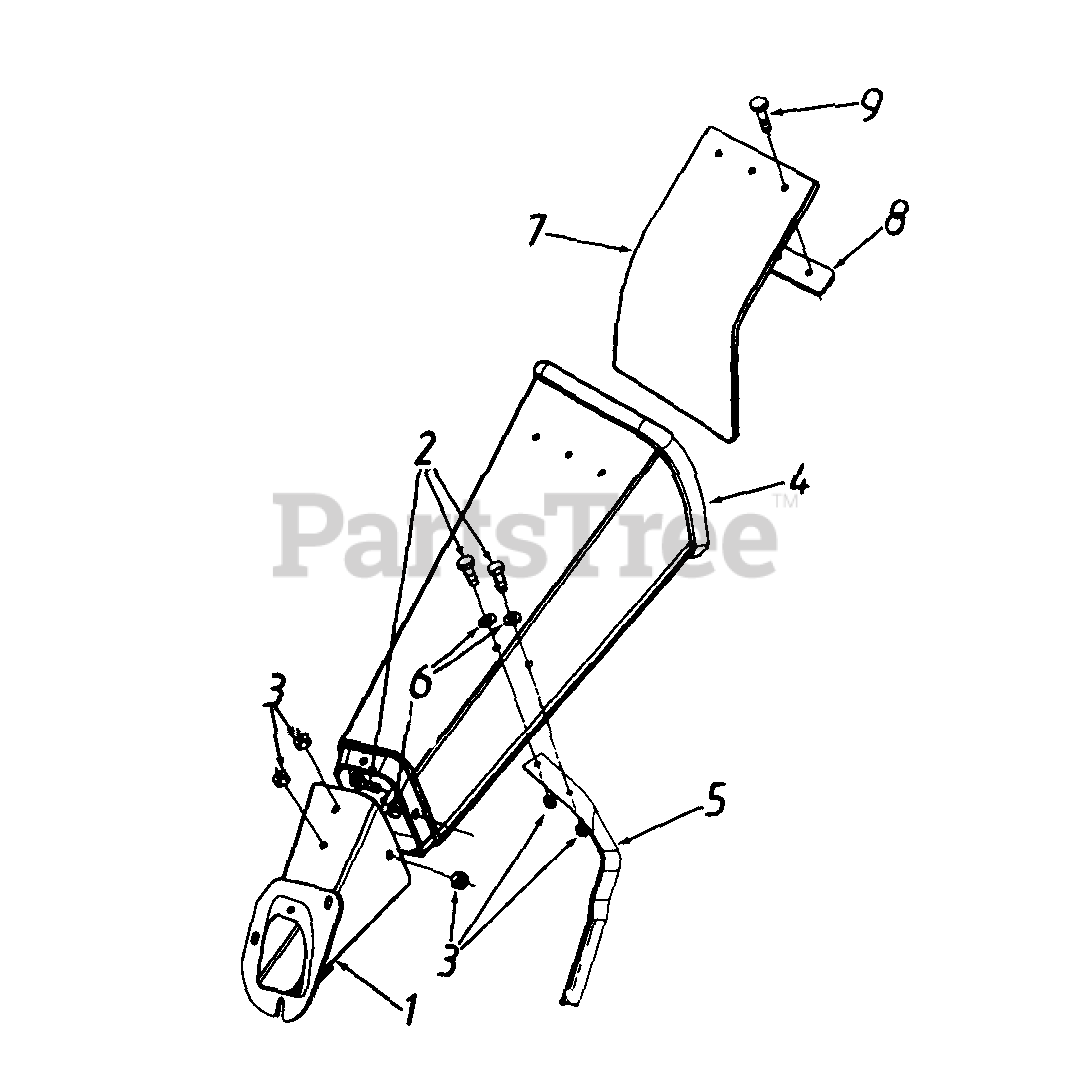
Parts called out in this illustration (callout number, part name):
3	NUT-LOCK
4	CHUTE -CH(PPER UPPER
5	FL-WASH..28" I.D. x .73" O.D.
8	STRIP-FLAP
9	RIVET
